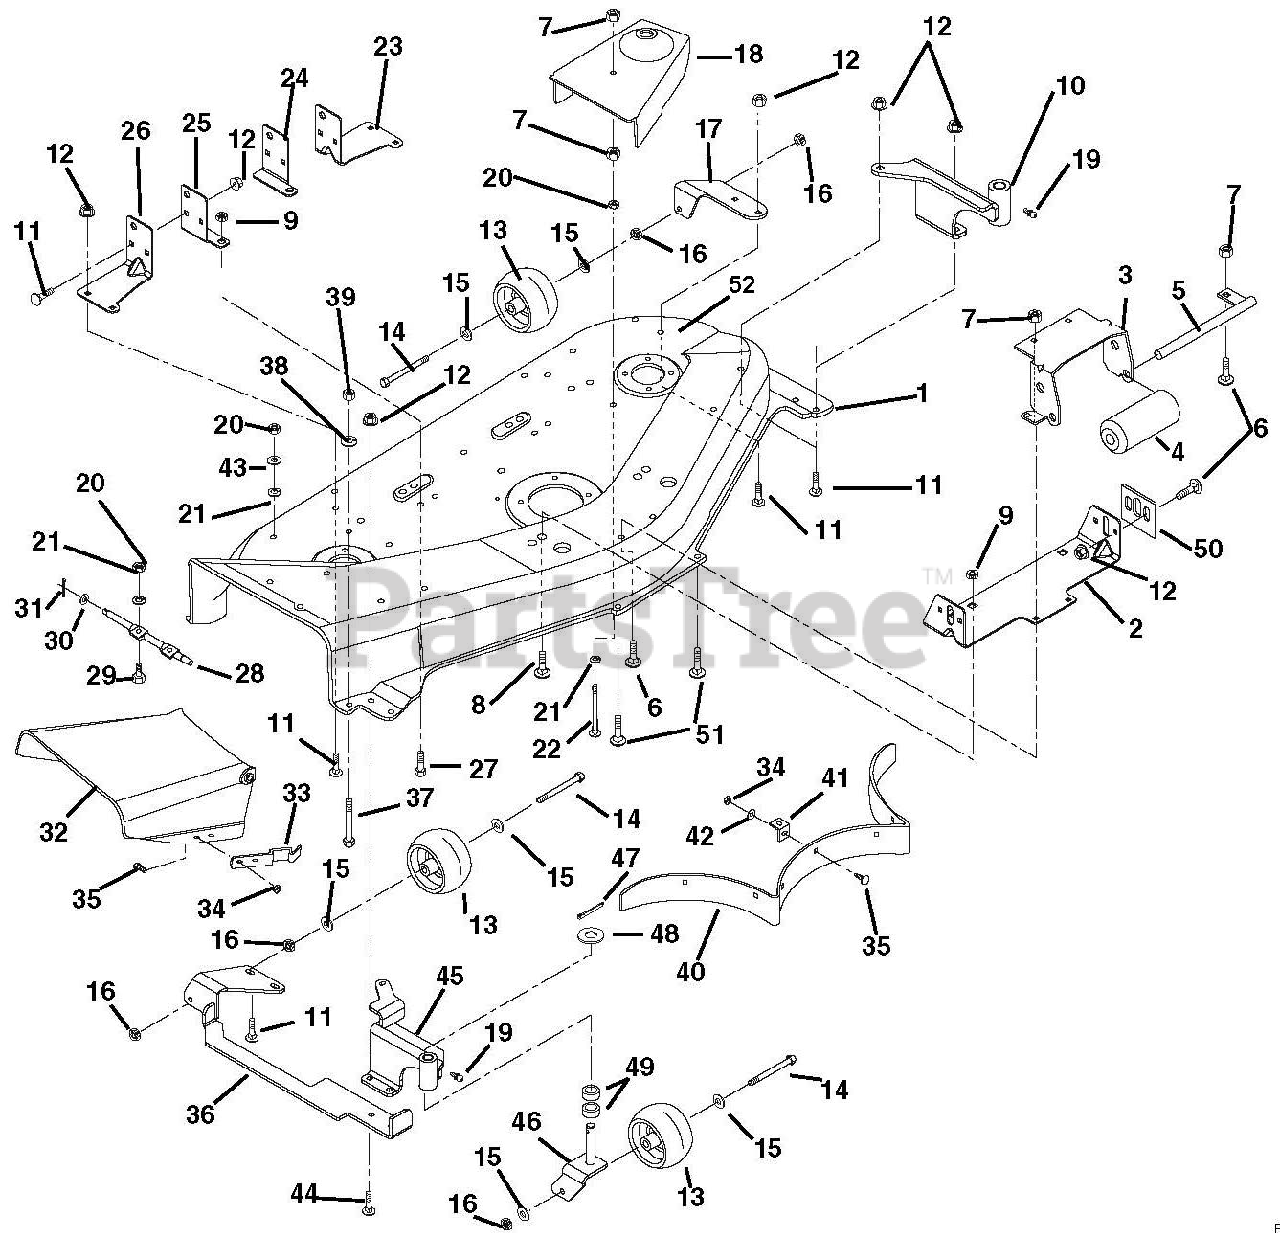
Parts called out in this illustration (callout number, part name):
1	MOWER PAN W/DECALS 48"- ORANGE
2	FRONT HANGER
3	BRACKET, ROLLER
5	ROLLER SHAFT
6	@BLT-RDHDSQNK .31-18X.75 G5YZ
7	@NUT-LK-CTR .31-18 YWZC
8	@BLT-RDHDSQNK .50-13X1.00 G5YZ
9	@NUT-LK-CTR .50-13 YWZC
10	WELDMENT-LEFT FRONT
11	BLT-RDHDSQSHK.31-18X.75 GR2 YW
12	@NUT-SPNLK-FLG .312-18 YWZC
14	@BLT-HEX .38-16X3.50 GR5 YWZC
15	@WSHR-FL-STL.38X.875X.083 YWZC
16	@NUT-LK-CTR .38-16 YWZC
17	BRACKET-LEFT REAR
18	R.H. BELT COVER
18	COVER, LEFT HAND
19	FTG-LUBE .25-28X.256 YWZC
20	@NUT-HEX .31-18 YWZC
21	WSHR-LK .312X.097 HVY YWZC
22	BLT-RDHDSQNK .31-18X3.25 SHTPL
23	LH REAR HANGER
24	LH REAR HANGER SUPPORT
25	RH REAR HANGER SUPPORT
26	RH REAR HANGER
27	@BLT-HEX .50-13X1.00 GR5 YWZC
28	HINGE PIN
29	@BLT-HEX .31-18X.75 GR5 YWZC
30	@WSHR-FL-STL.406X.812X.065 YWZ
31	@PIN-CTR .09X.75 EXTPRSQCT YWZ
32	CHUTE EXTENSION
33	FLAT SPRING - ORANGE
34	@NUT-LK-CTR .25-20 YWZC
35	BLT-RDHDSQSHNK.25-20X.50 YWZC
36	WELDMENT-RIGHT REAR
37	@BLT-HEX .38-16X2.50 GR5 YWZC
38	WSHR-LK .375X.115 HVY YWZC
39	@NUT-HEX .38-16 YWZC
40	BAFFLE
41	BAFFLE TAB
42	@WSHR-FL-STL.281X.62X.065 YWZC
43	@WSHR-FL-STL.312X.734X.065 YWZ
44	@BLT-RDHDSQNK .31-18X1.00 G5YZ
45	WELDMENT-RIGHT FRONT
46	WELDMENT-CASTER FORK
47	@PIN-CTR .18X1.25 EXTPRSQCT YZ
48	WSHR-FL-STL .630X1.005X.062 YZ
49	BSHG-SLV .625X.750X.500 BR
50	MOWER ADJUSTMENT TAB
51	@BLT-RDHDSQNK .31-18X1.50 G5YZ
52	48 IN DECK
